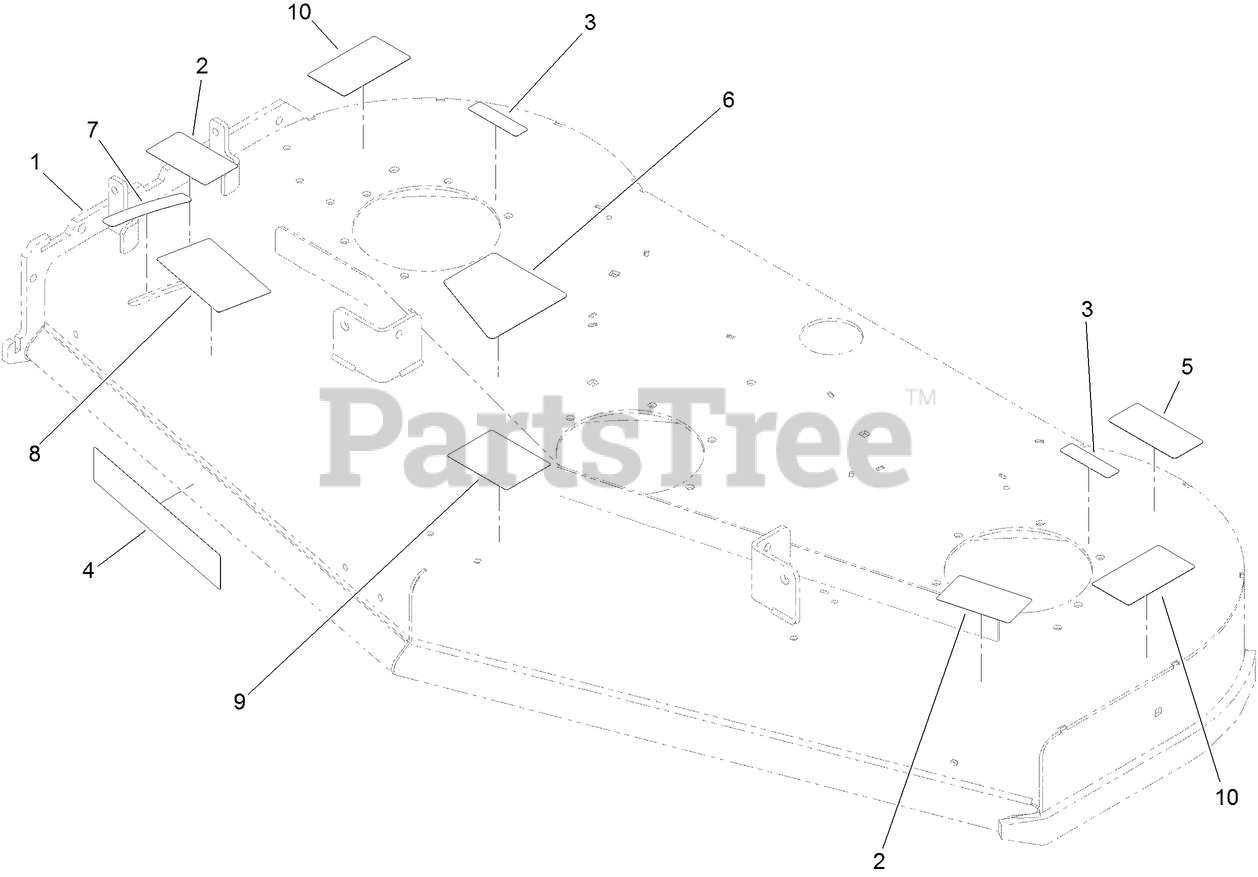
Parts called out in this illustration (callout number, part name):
1	DECK ASM
2	DECAL-DANGER
3	DECAL-DANGER
5	DECAL-TORQUE, BLADE BOLT
6	DECAL-BELT TENSION, CE
7	DECAL-SETTING, BAFFLE
8	DECAL-ADJUSTMENT, BAFFLE
9	DECAL-SCALP, ANTI
10	DECAL-DANGER, ROTATING PARTS
